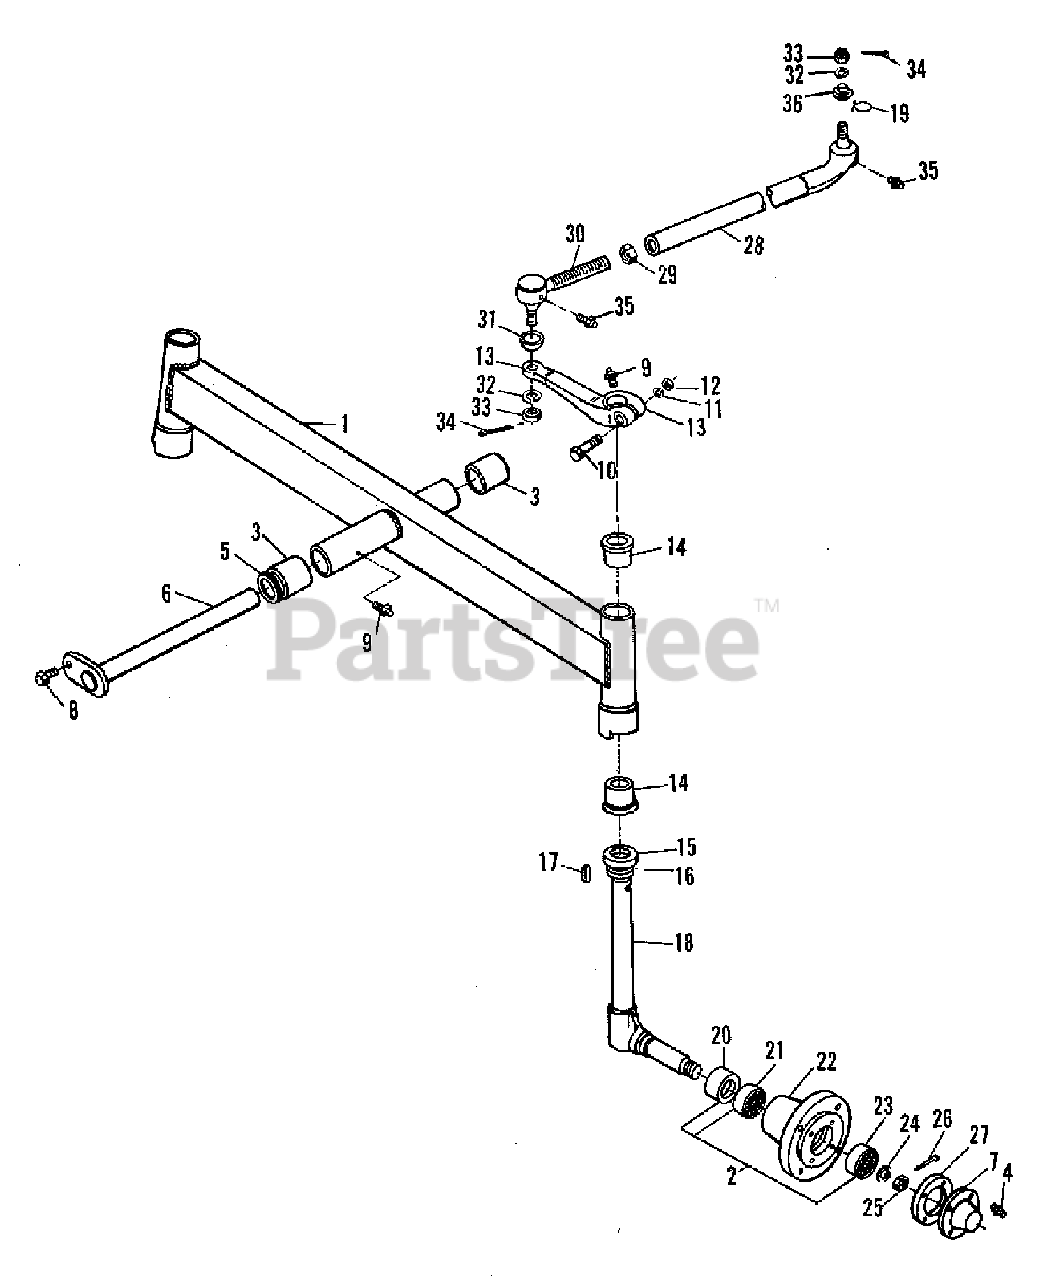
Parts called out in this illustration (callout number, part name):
1	AXLE, front
2	BEARING KIT, wheel (Incl. Items 20, 21, 23)
4	SCREW, M6 x 12
5	WASHER 1.6
5	WASHER 2.3
6	PIN, pivot
8	CAPSCREW, M10 X 20
9	FITTING, lube
11	LOCKWASHER, M12
13	ARM, steering
18	SPINDLE, L.H.
18	SPINDLE, R.H.
20	SEAL, oil
22	HUB (For Turf Wheel)
26	PIN, cotter
27	GASKET, cap
28	ROD, L.H., tie
28	ROD, R.H., tie
29	NUT, R.H. threaded
29	NUT, L.H. threaded
30	END, tie rod
31	COVER, dust
32	LOCKWASHER, M12
34	PIN. Cotter
35	FITTING, lube
36	COVER, dust
